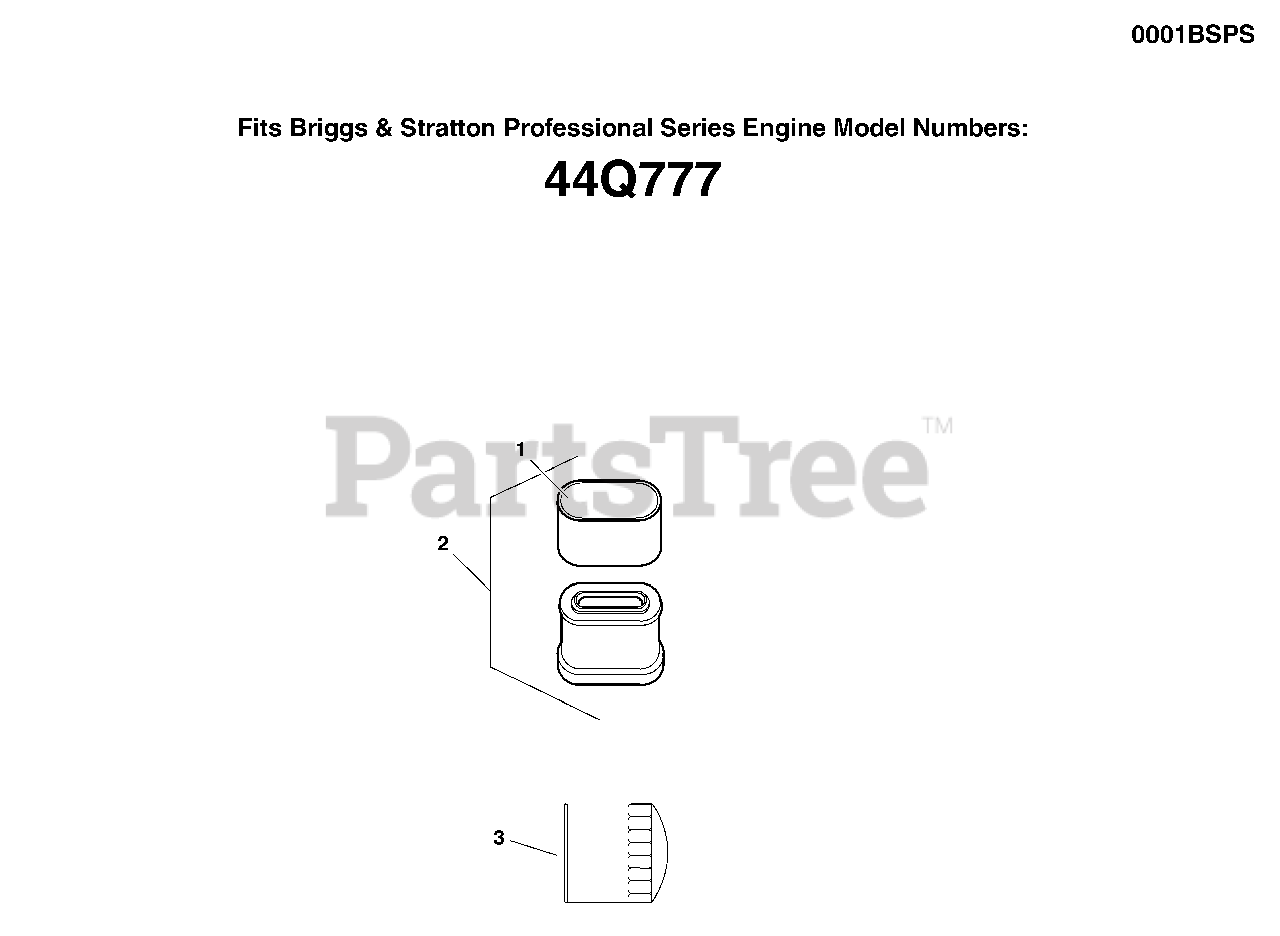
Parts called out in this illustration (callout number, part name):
1	FILTER-PRE CLEANER
2	AIR CLEANER ELEMENT, 26HP ELS, B & S
3	OIL FILTER, 26HP ELS, BRIGGS & STRATTON
